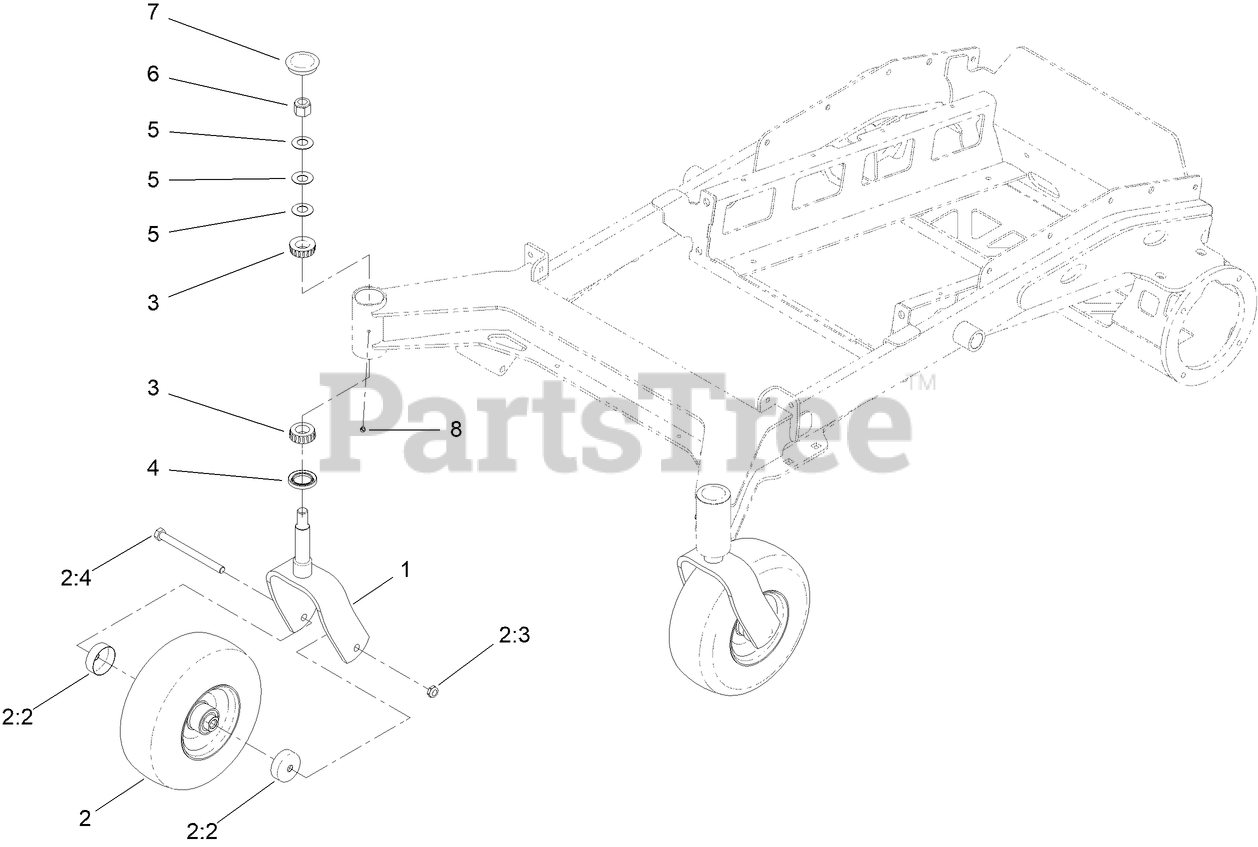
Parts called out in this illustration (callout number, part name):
1	FORK-CASTER
2	MF WHEEL TIRE BEARING ASM
2:2	GUARD-SEAL
2:3	NUT-HEX
2:4	SCREW-HH
3	BEARING-ROLLER, TAPERED
4	SEAL-GREASE
5	WASHER-BELLVILLE
6	NUT-LOCK, NI
7	CAP, GREASE
